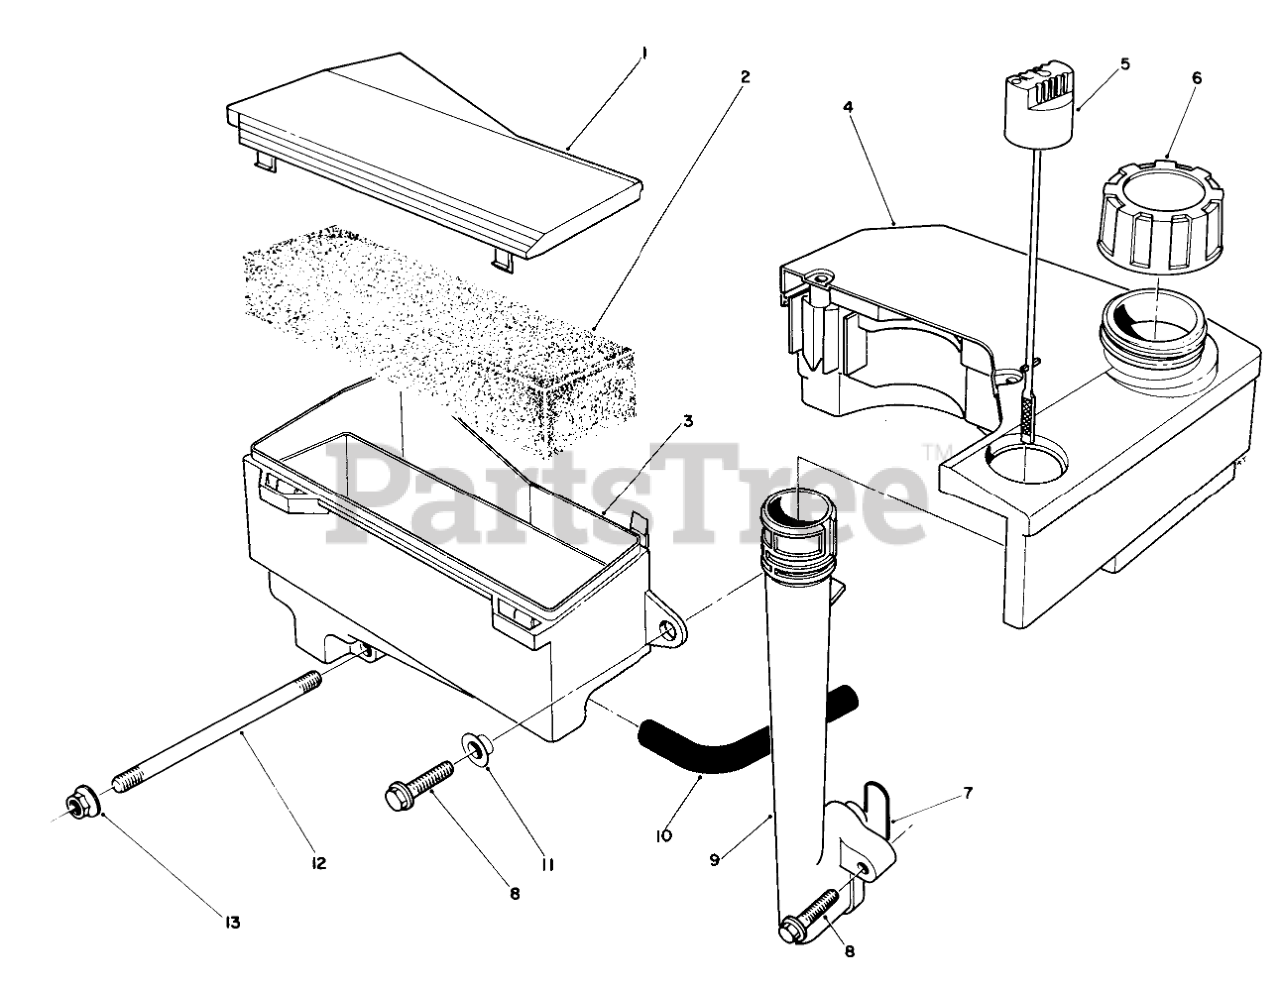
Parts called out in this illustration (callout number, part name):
1	AIR CLEANER CAP
3	Body-Air Cleaner
4	TANK ASM
5	Dipstick
6	GAS CAP ASM
7	O-RING
11	SPACER
12	Stud-Carburetor
